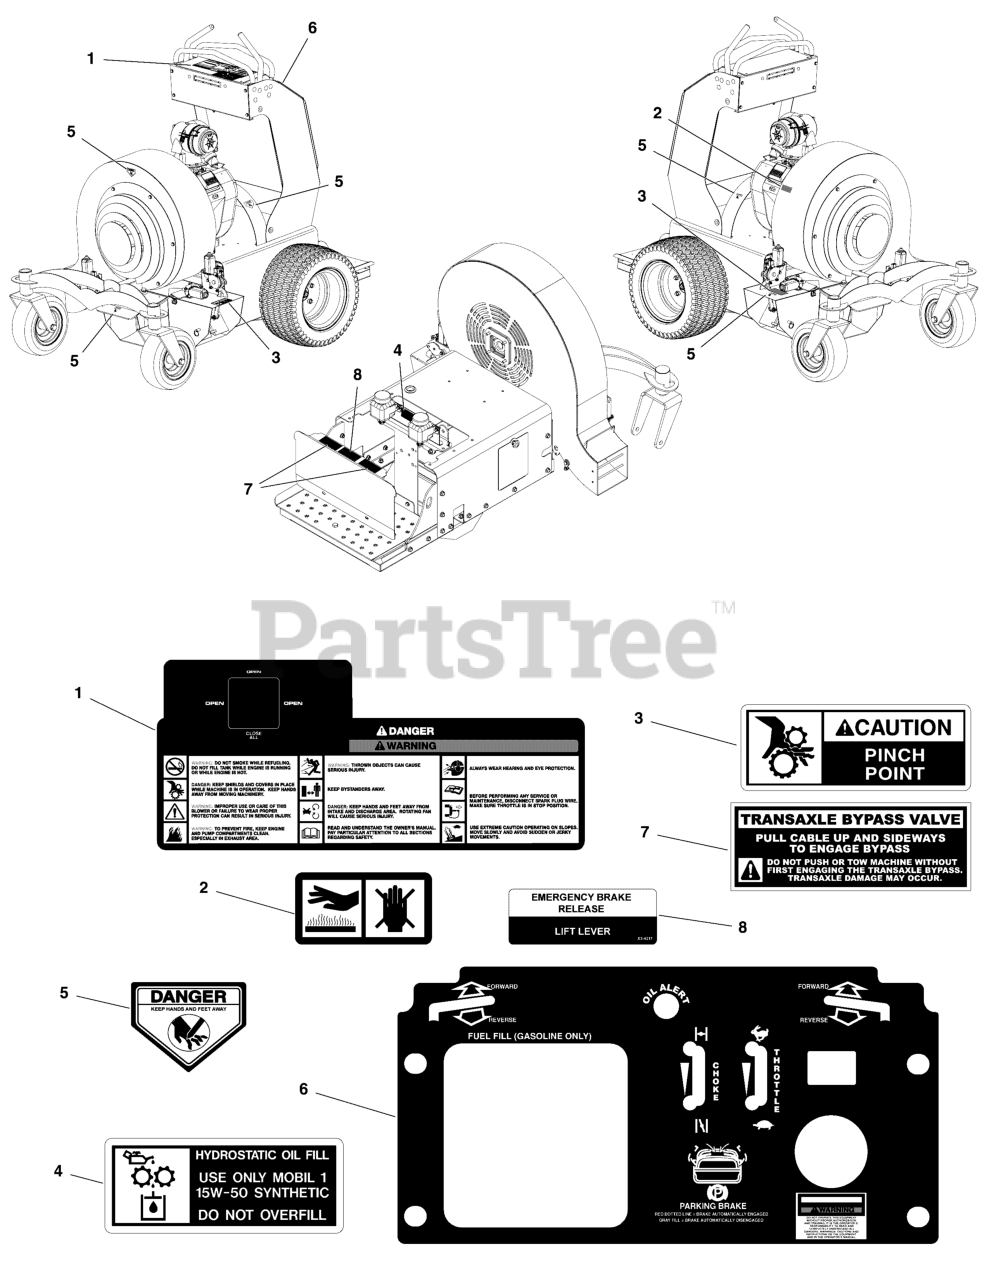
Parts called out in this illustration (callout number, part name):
1	DECAL, DASH, JOYSTICK
2	DECAL, HOT
3	DECAL, PINCH
4	DECAL, HYDRO
5	DECAL, DANGER
6	DECAL, DASH CONTROLS
7	DECAL, TRANS BYPASS
8	DECAL, EMERGENCY BRAKE RELEASE
